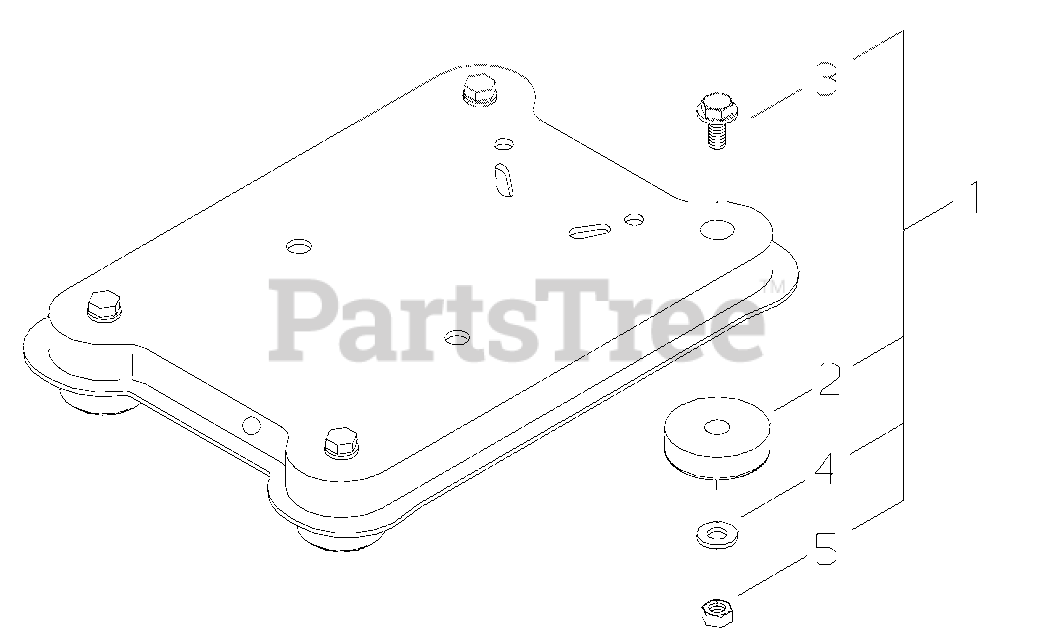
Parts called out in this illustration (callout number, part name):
1	BASE ASSY, PUMP
2	CUSHION
3	BOLT M6×16
4	WASHER Ø19
